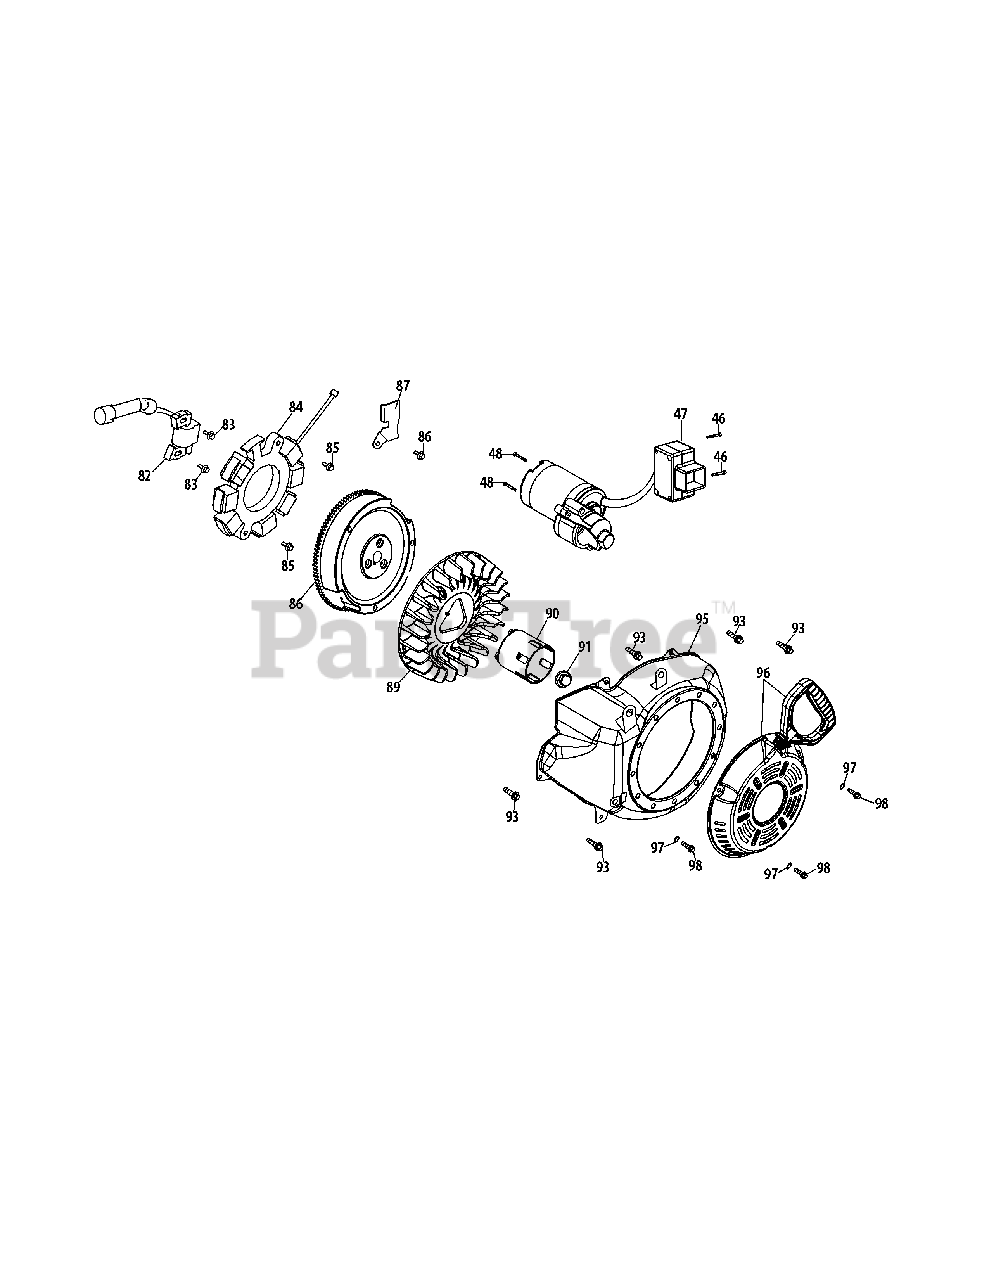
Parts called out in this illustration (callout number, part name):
46	Bolt M4×55
47	Electric Starter
48	Bolt M8×55
82	Ignition Coil Assembly
83	Ignition Coil Bolt
84	Coil Assy.Charge
85	Bolt M6×30
86	Bolt M6×8
87	Alternator Wire Clamp Brkt
89	Fan,Cooling
90	Pulley,Starter
91	Nut, Special M16×1.5
92	Bolt M6×16
93	Bolt M6×12
95	Blower Housing
96	Recoil Starter
97	Gasket 6
98	Bolt M6×10
